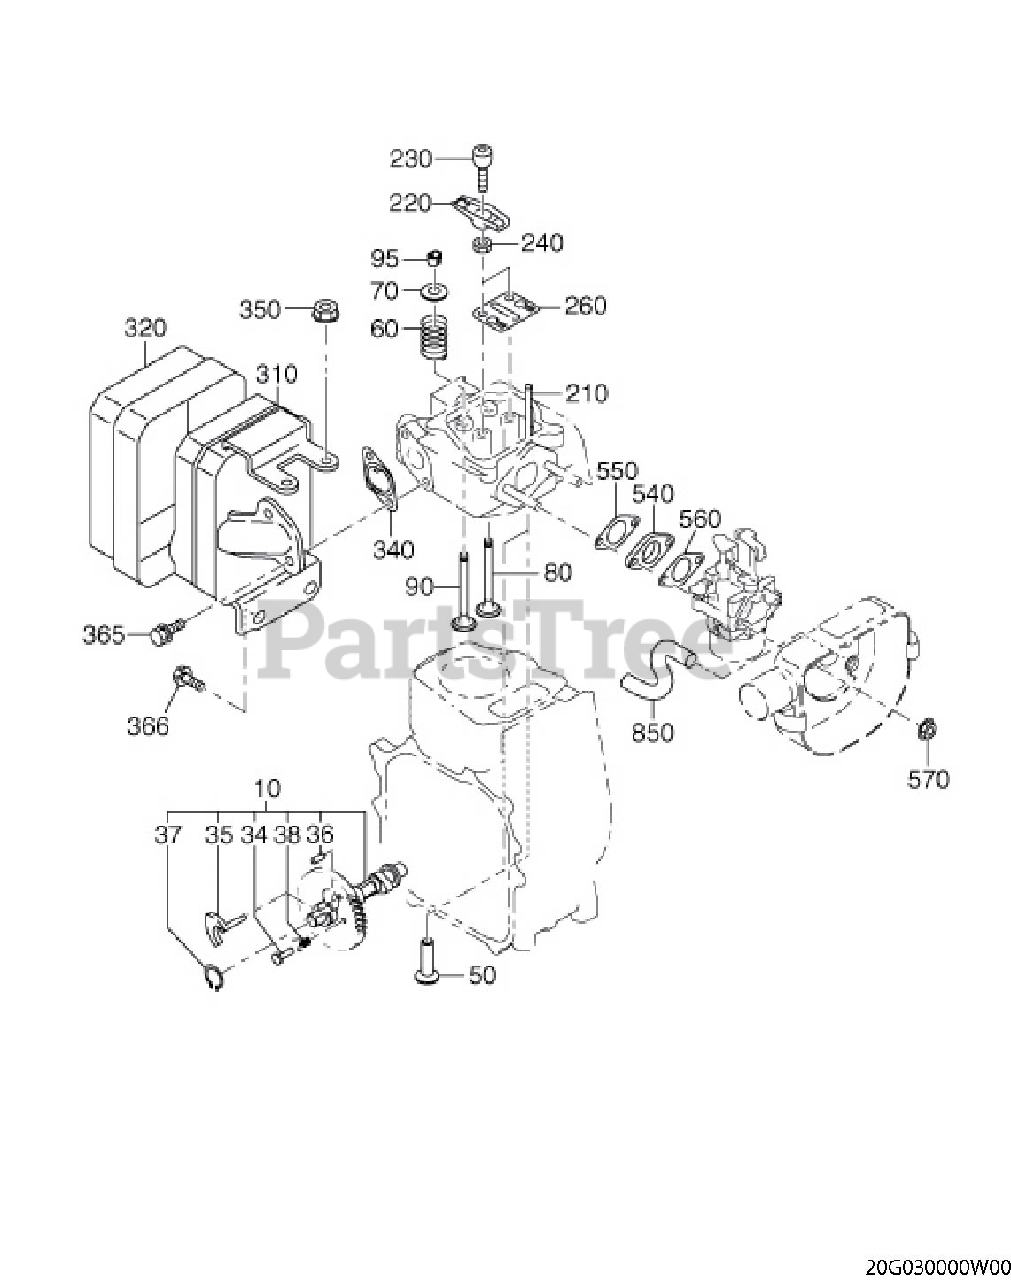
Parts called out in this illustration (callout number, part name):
50	TAPPET
70	SPRING RETAINER
340	GASKET (EXHAUST)
366	BOLT AND WASHER AY
550	GASKET (INTAKE)
